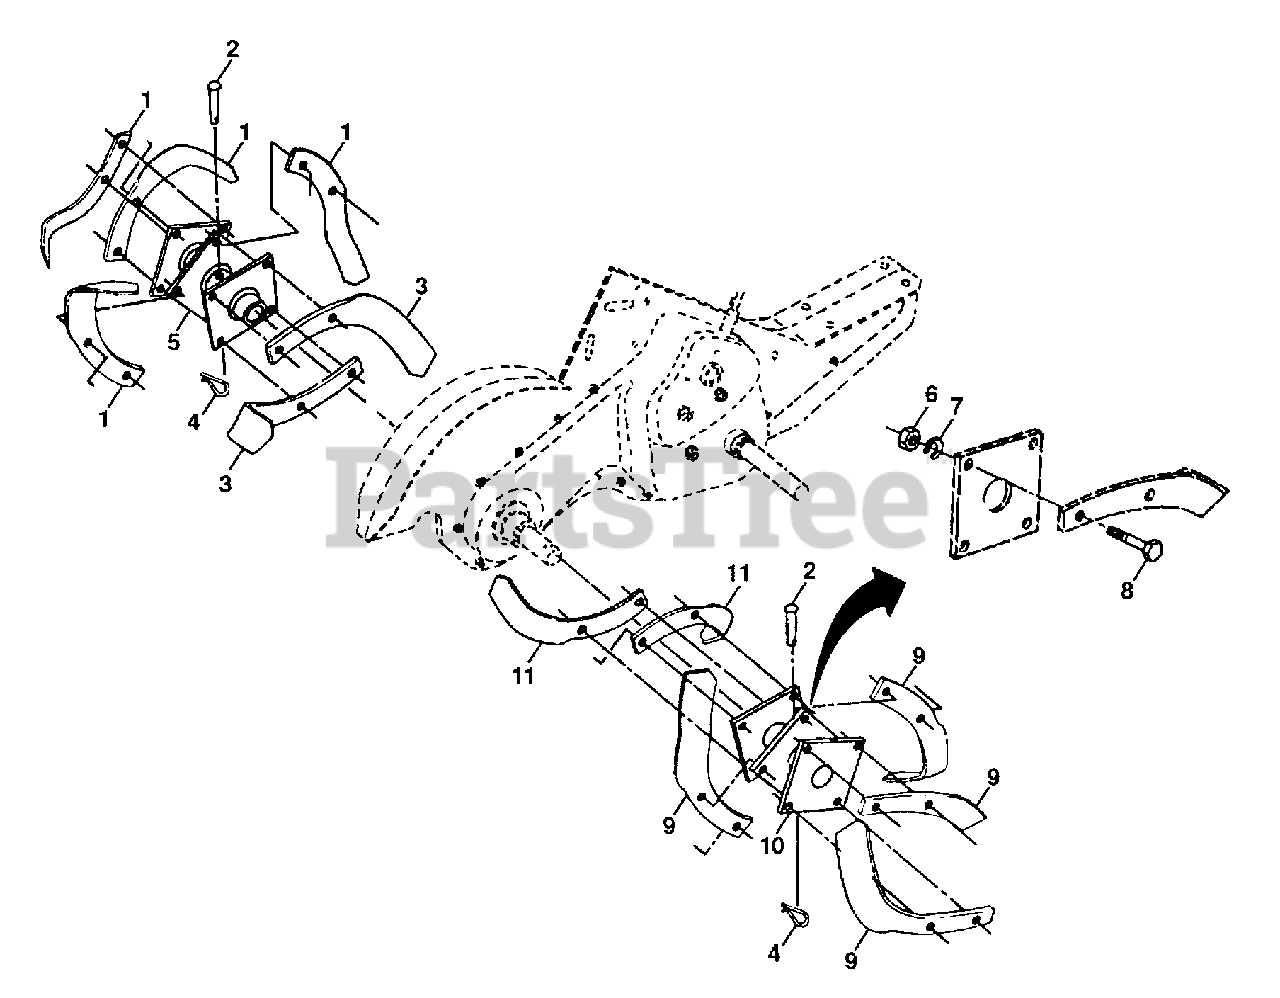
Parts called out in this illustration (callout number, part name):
2	PIN.CLEVIS.SHEAR
3	"TINE.LH.12"""
4	RETAINER.SPRING
5	HUB&PLATE ASM LH
7	LOCKWASHER
8	BOLT
10	HUB&PLATE ASM RH
11	"TINE.RH.12"""
